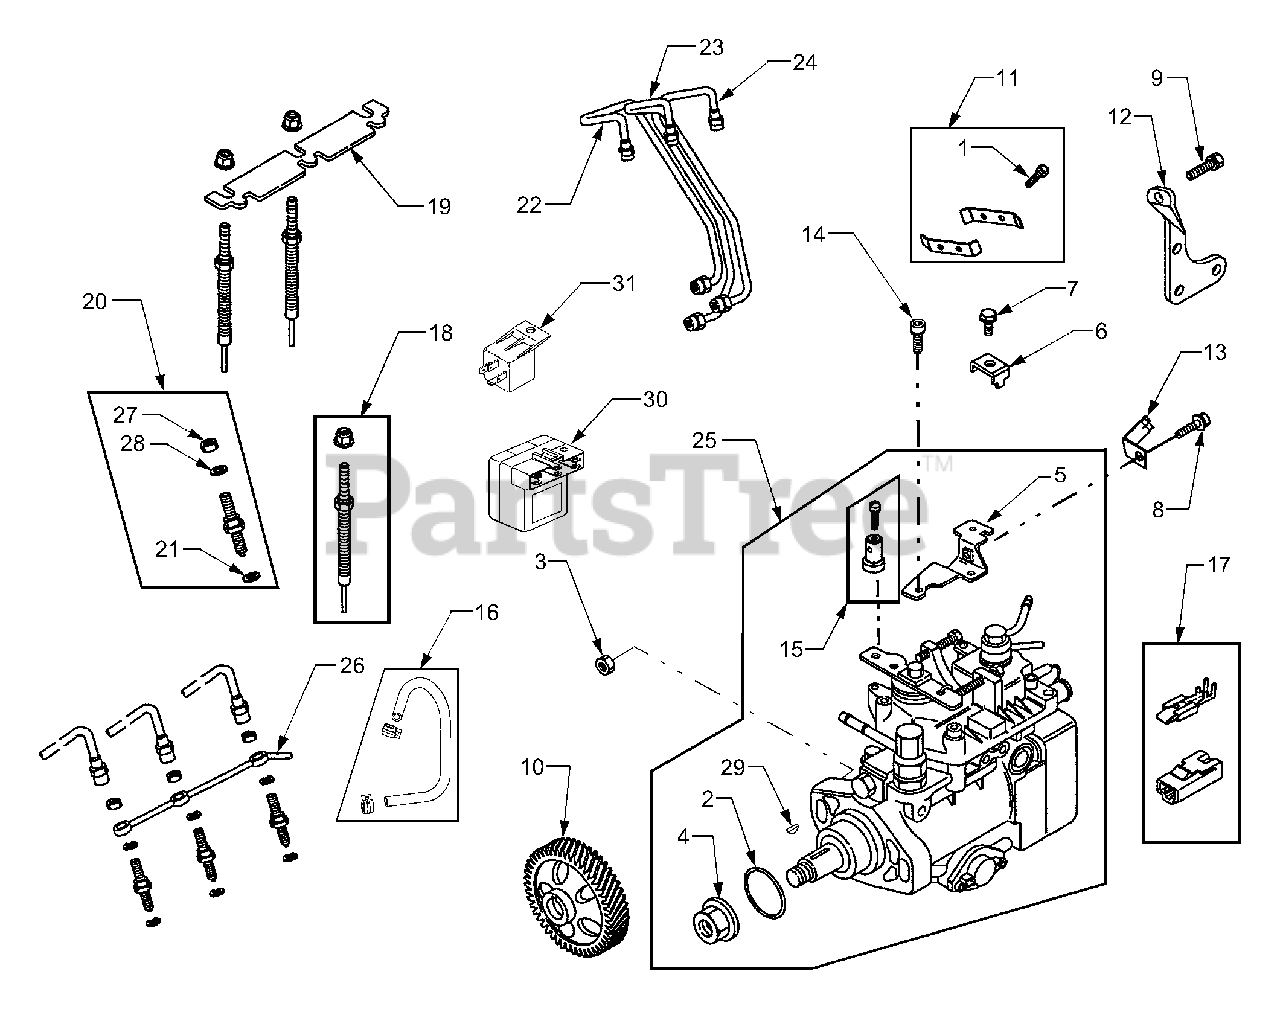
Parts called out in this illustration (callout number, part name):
1	Screw, Hex, 6mm
2	Seal, O-Ring
3	Nut, Hex Metric
4	Nut, Hex Metric
5	Bracket, Casing Clamp
6	Clamp, Casing
7	Screw, Casing Clamp
8	Screw, Support Bracket
9	Screw, Support Bracket
10	Gear, Drive
12	Bracket, Support
13	Bracket, Support
14	Screw, Casing Clamp Bracket
15	Clamp, Swivel
16	Hose/Clamp Ass'y., Fuel Return
17	Connector, Injection Pump
18	Plug, Glow
19	Strap, Glow Plug
20	Nozzle, Injector
21	Seat, Injector
22	Pipe, Injector #1
23	Pipe, Injector #2
24	Pipe, Injector #3
25	Pump, Injection
26	Pipe, Fuel Return
27	Nut, Hex Injector Nozzle
28	Washer, Injector Nozzle
29	Key, Woodruff
30	Module, Pre Heat
